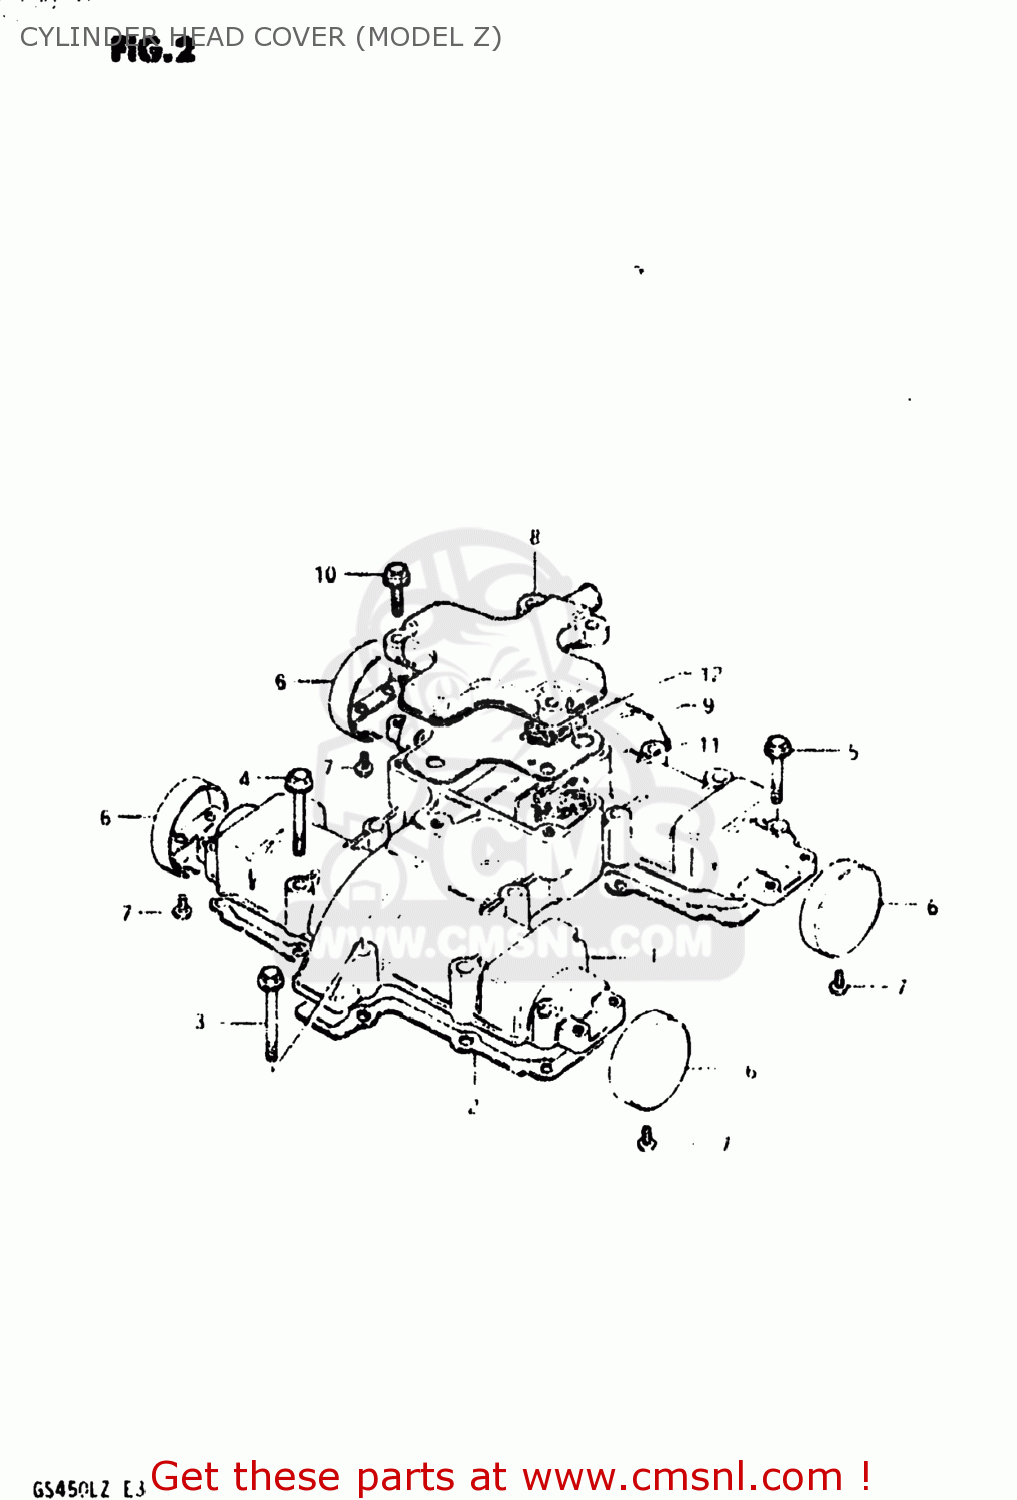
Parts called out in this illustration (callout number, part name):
1	COVER,CYLINDER HEAD
2	GASKET,CYLINDER HEAD COVER (MCA)
3	BOLT,UNDER
4	BOLT
5	BOLT
6	CAP,CYLINDER HEAD COVER
7	SCREW
8	COVER,BREATHER
9	GASKET (MCA)
10	BOLT,REAR
11	COVER,BREATHER
12	SEPARATOR,OIL BREATHER
